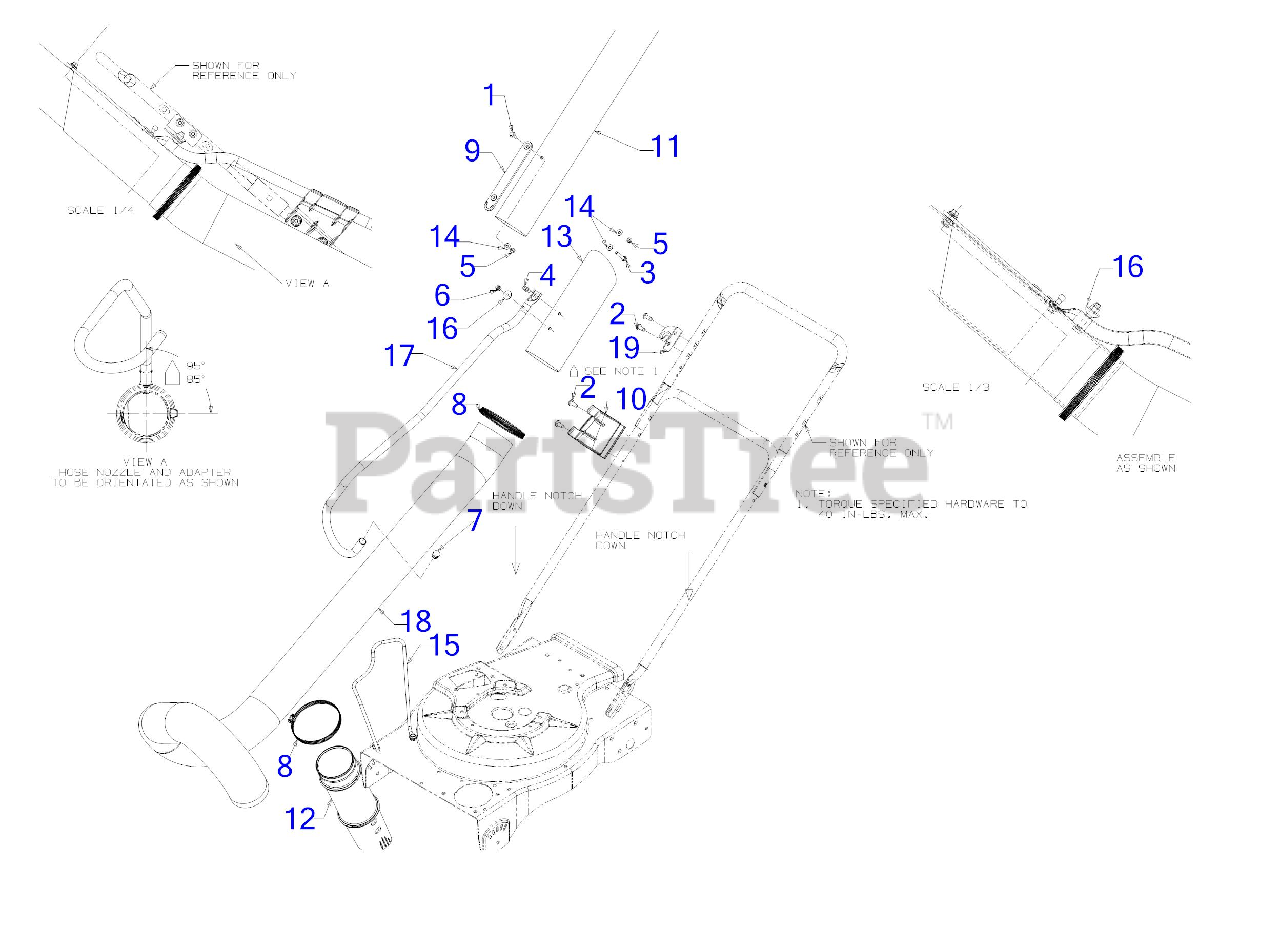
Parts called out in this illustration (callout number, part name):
1	SCREW 1/4-20 x .75 GR5
2	SCREW 5/16-18 x .750
3	BOLT 1/4-20X1.62 GR5
4	PIN 1/4-20
5	HEX NUT
6	HEX ACORN NUT
7	HANDLE PLUG
8	HOSE CLAMP
9	CHUTE STRAP
10	CLIP-HANDLE NOZZ
11	NOZZLE EXTENSION 3.625 x 31.00
12	VAC HOSE ADAPTER
13	HOSE NOZZLE 3.875
14	FLAT WASHER .271:.630:.065
15	HOLDER ROD
16	HOSE HANGER SPACER
18	VACUUM HOSE 4.0 x 75.0
19	UPPER HANDLE BRACKET
